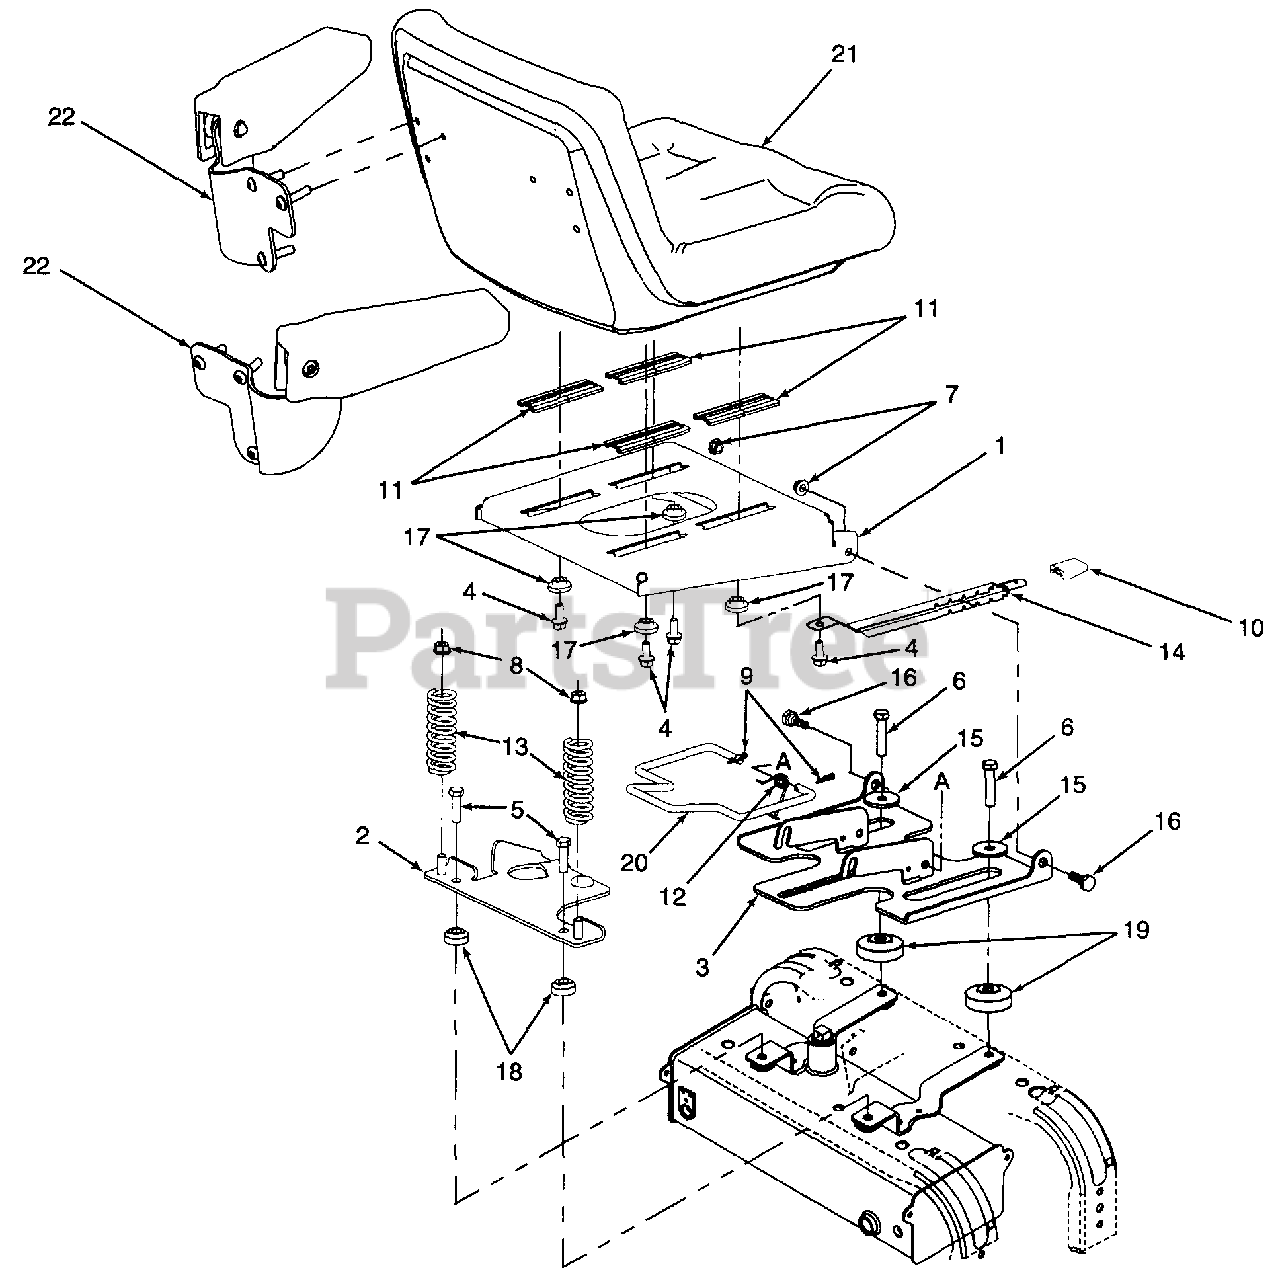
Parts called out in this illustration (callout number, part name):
1	Seat Base
4	Screw, Hex Wash Hd Tapp 5/16-18 x .75
5	Screw, Hex Cap 3/8-16 x 1.5 GR5
6	Screw, Hex Cap 3/8-16 x 1-3/4 GR5
7	Nut, Hex Flange Lock 5/16-18 GR5
8	Nut, Hex Flange Lock 3/8-16 GR5
9	Pin, Internal Cotter
10	Knob, Seat Adjustment
11	Seat Slide
12	Spring, Torsion
13	Spring, Compression
14	Spring, Index
15	Washer, Flat, .390 x 1.5 x .134
16	Bolt, Shoulder .437 x .268:5/16-18
17	Spacer, Shoulder, .38 I.D.
18	Spacer, Shoulder
19	Spacer, Seat Pan Shoulder
20	Rod, Seat Pan Lock
21	Seat Assembly
22	Seat Arm
